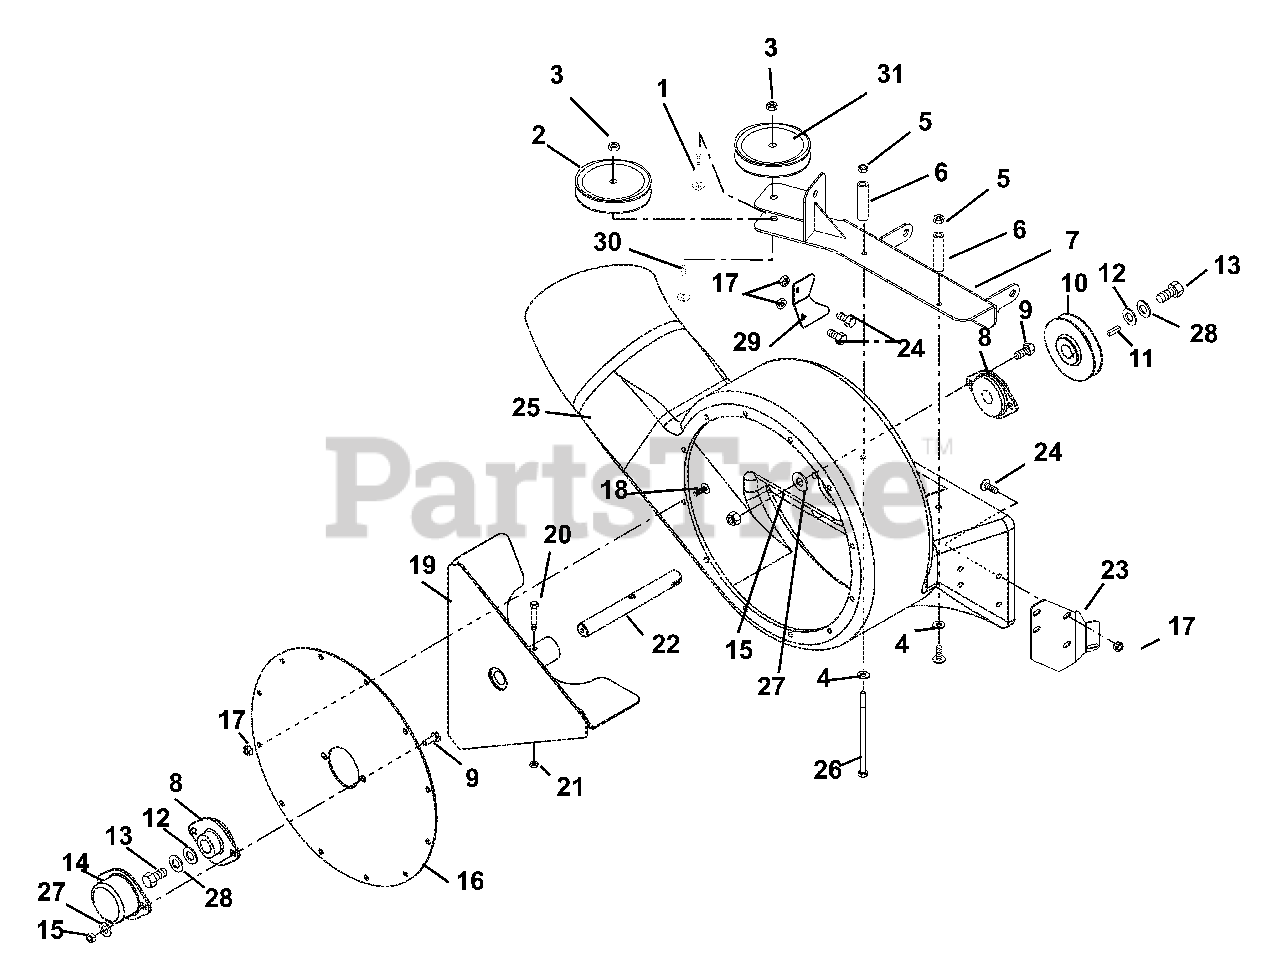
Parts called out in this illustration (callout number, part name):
1	Bolt-Round Head Square Neck.38-16 x 1.50 Grade 5
2	Idler-V 4.00 x .38
3	Nut-Locking-Flange .38-16
4	Washer-Flat-Steel .281 x .62 x.065
5	Nut-Locking-Center .25-20
6	Spacer-.33 ID x .50 OD x 4.63
7	Weldment- Bracket- Mounting
8	Bearing, 2 Bolt Flange-.75 ID
9	Bolt-Hex .31-18 x 1.00 Grade 5
10	Pulley, Driven 3.50
11	Key-Square .187 x .50 x .187
11	(Gravely Part Number)
12	Washer-.328 x 1.0 x .094
13	Bolt-Hex .25-28 x .75 Grade 5
14	Cover-Bearing
15	Nut-Locking-Nylon .312-18
16	Plate-Bearing Mount
17	Nut-Locking-Flange .250-20
18	Screw-Machine .250-20 x .50
19	Impeller-Grass Pump
20	Bolt-Hex .25-20 x 1.50 Grade 5
21	Nut-Locking-Center .25-20
22	Shaft, Grass Pump
23	Bracket, Mounting, Deck To Pump
24	Screw-Machine .25-20 x .75
25	Housing, Grass Pump
26	Bolt-Hex .25-20 x 4.5 Grade 5
27	Washer-Flat-Steel .31 x .73 x.065
28	Washer-Lock .25 x .062
29	Bracket-Deck Stop
30	Bolt-Round Head Square Neck.38-16X1.25 Grade 5
31	Idler Flanged 3.50
